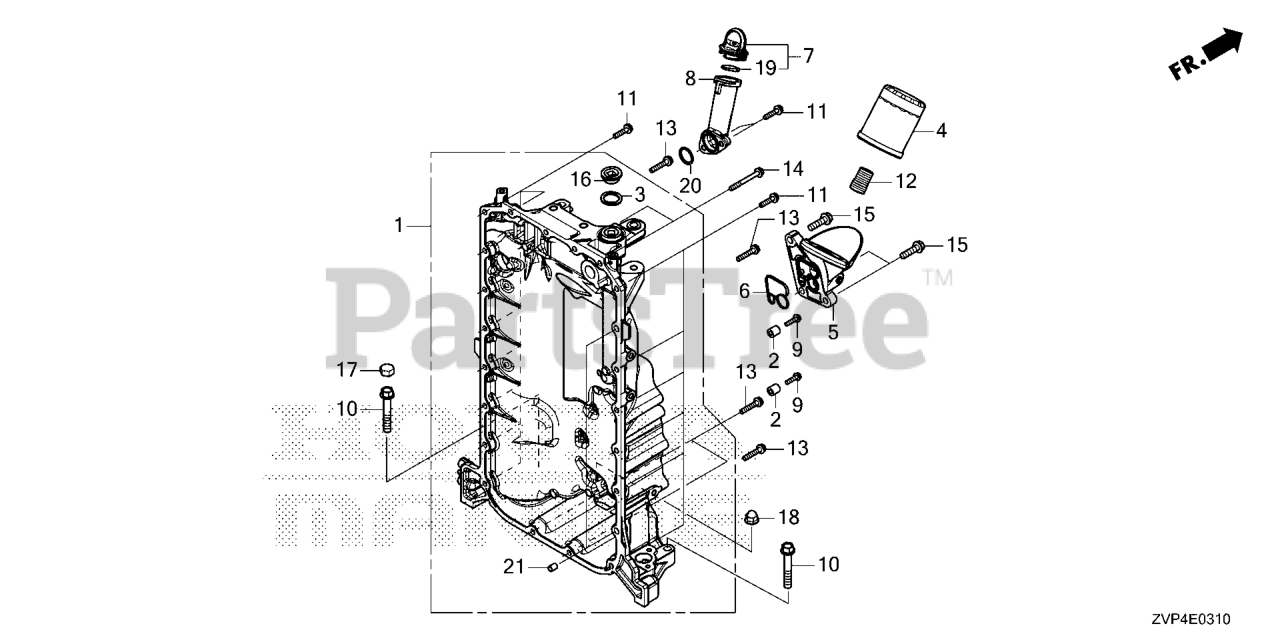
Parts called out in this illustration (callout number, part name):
1	CRANKCASE COMP
2	METAL, ANODE
3	WASHER, SEALING (22MM)
4	FILTER, OIL
5	FLANGE COMP
6	PKG, OIL FILTER BASE
7	CAP ASSY., OIL FILLER
8	EXTENSION, OIL FILLER
9	BOLT, FLANGE (5X20)
10	BOLT, FLANGE (10X60)
11	BOLT, FLANGE (6X25)
12	HOLDER, OIL FILTER
13	BOLT, FLANGE (6X32)
14	BOLT, FLANGE (6X55)
15	BOLT, FLANGE (8X30)
16	BOLT, SEALING (22MM)
17	CAP, BOLT (10MM)
18	NUT (10MM)
19	O-RING (18.1X3.6)
20	O-RING (28.3X2.4) (NOK)
21	PIN A, DOWEL (8X14)
